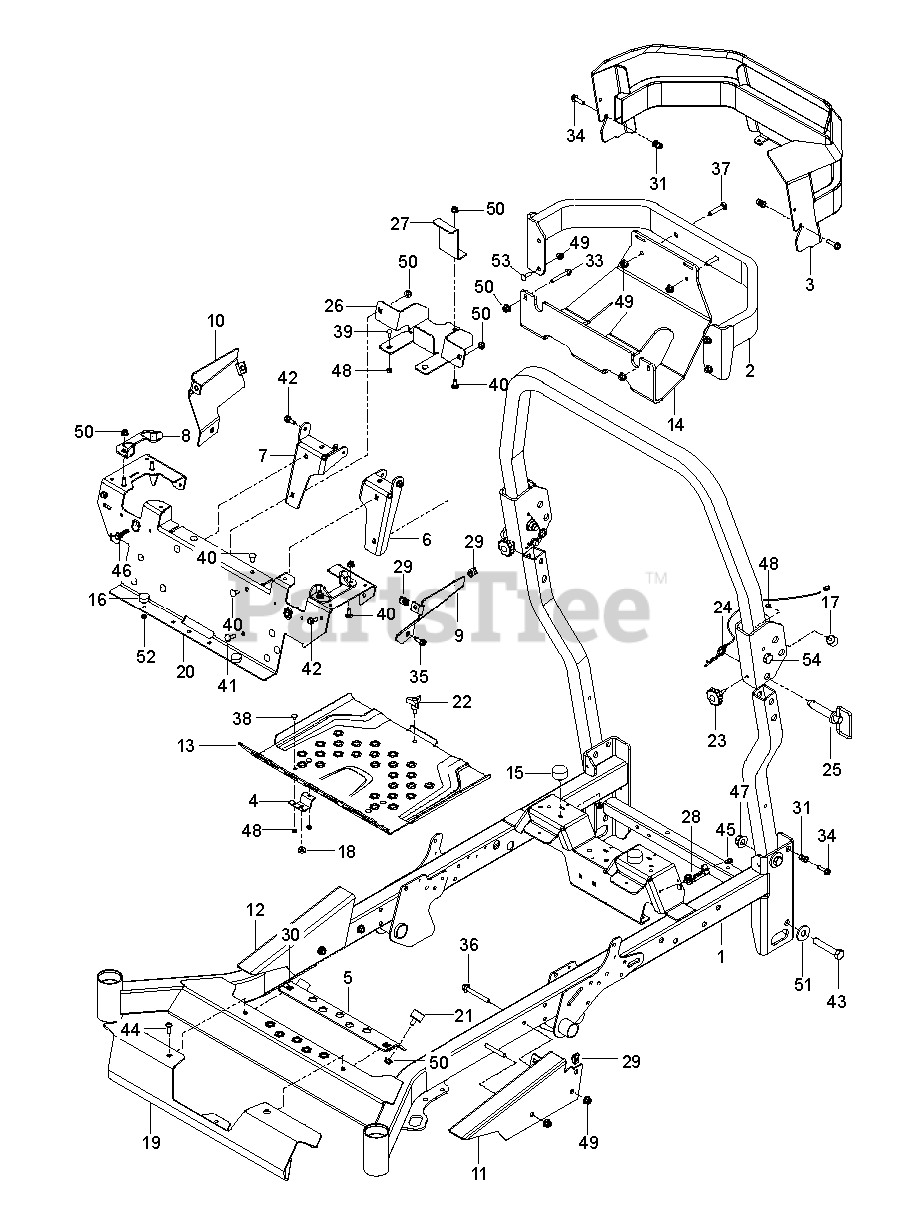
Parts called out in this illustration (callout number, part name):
1	FRAME.W/DECALS.48-60".ORG
2	BUMPER.REAR.ORANGE
3	GUARD.PNT.ENGINE.GREY
4	COVER.PNT.VALANCE.PZ.GREY
5	BRACKET.PNT.ISOLATOR.SUPPT.BLK
6	BRACKET.PNT.MTG.SEAT.LH.EDIP
7	BRACKET.PNT.MTG.SEAT.RH.EDIP
8	CABLE.YOKE.PARK.BRAKE
9	PANEL CLOSE OUT LH ORANGE MS-6
10	PANEL CLOSE OUT RH ORANGE MS-6
11	PANEL.PNT.WEDGE.LH.ORG
12	PANEL.PNT.WEDGE.RH.ORG
13	PLATE.PNT.FOOTREST.PZ.ORANGE
14	PLATE SKID, Z500 LONG YAMAHA G
15	BUMPER 5/16-18
16	BUMPER, 1/4-20 STUD, 1/4
17	BUMPER, MALE STUD, 1/4-20
18	GROMMET, BUMPER
19	COVER.PNT.VALANCE.PZ.GREY
20	CROSS.MEMBER.PNT.SEAT.FRONT.OR
21	ISOLATOR.PZ.FOOTREST
22	KNOB W/STUD
23	KNOB.5/16-18X1"BLACK
24	PIN.HAIR.DOUBLE.LOOP.W/LANYARD
25	PIN.ROPS.W/HANDLE
26	PLATE.PNT.BATTERY.EDIP
27	BRACKET.PNT.MOUNT.BATTERY.EDIP
28	BRACKET.FUSE.RELAY.HOUSING.PZ
29	U-CLIP 5/16-18 NUT RETAINER
30	SCREW.BUTTON.HEAD.TORX.3/8-161
31	NUTSERT 5/16-18 THICK GRIP
33	HHFS 5/16-18 X 2.25 GD 5
34	HHFS 5/16-18 X 1.25 TPBLT GD 5
35	SCREW
36	HHFS 3/8-16 X 3 GRD 5 ZD
37	RHSNB 3/8C X 2
38	BOLT
39	1/4-20X3/4 CARR BLT
40	BOLT 5/16C X 3/4" CARRIAGE
41	RHSNB 5/16C X 1
42	BOLT, SHOULDER
43	5/8-11 X 3-1/2 HHB GRADE 5
44	SCREW.BUTTON.HEAD.TORX.3/8-161
45	SCREW
46	SCREW.SHAKEPROOF.1.25.BLACK
47	NUT 5/8-11 FLG NYLOC ZD
48	NUT.1/4-20.HEX.NYLOC.ZD
49	NUT 3/8-16 HEX FLG NYLOC ZD
50	5/16-18 NYLOC FLANGE NUT
51	WASHER, 5/8 FLAT
52	JAM NUT 1/4C (2 2 PW01)
53	BOLT.3/8-14X1.25
54	BOLT.HEXAG.5/8-11X4-1/4.G5.ZPY
